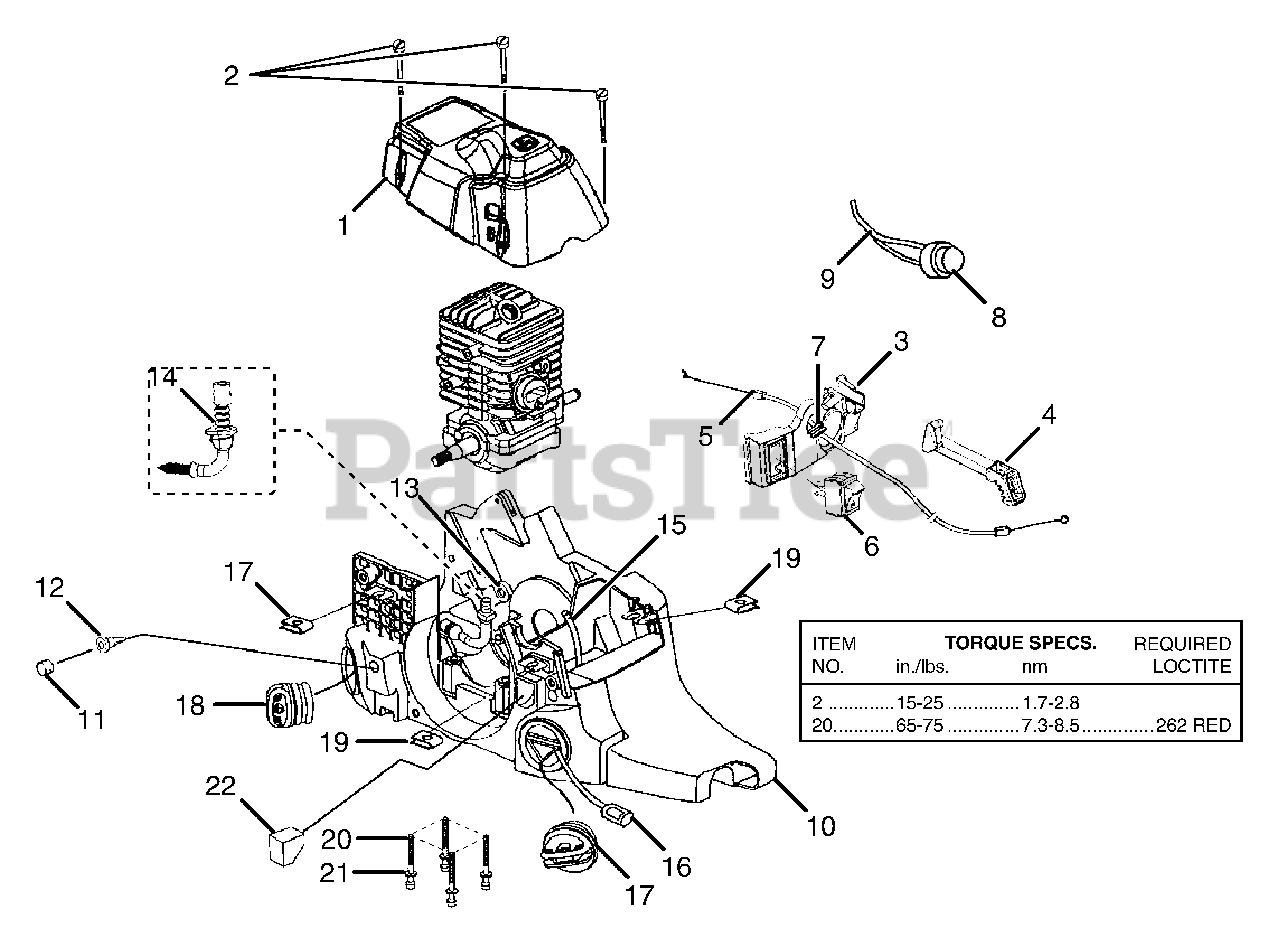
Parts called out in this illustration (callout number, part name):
1	CYLINDER COVER
2	SCREW (10-16 X 1.5 PAN HD.)
3	CONTROL PANEL
4	ROD, CHOKE
5	THROTTLE CABLE
6	SWITCH, ROCKER
7	GROMMET - SPLIT
8	PRIMER BULB
9	RUBBER TUBING (5-1/2 in.)
10	CHASSIS ASSEMBLY (45CC)
11	ELEMENT, FILTER
12	DUCK BILL VALVE
13	OIL OUTLET GROMMET
14	OIL INTAKE TUBE W/FILTER
15	RUBBER TUBING (8-1/2 in.)
16	FUEL FILTER
17	FUEL CAP W/RETAINER
18	OIL CAP W/RETAINER
19	SPEED NUT
20	SCREW (10-24 x 2 in.)
21	WASHER
22	PRE FILTER
